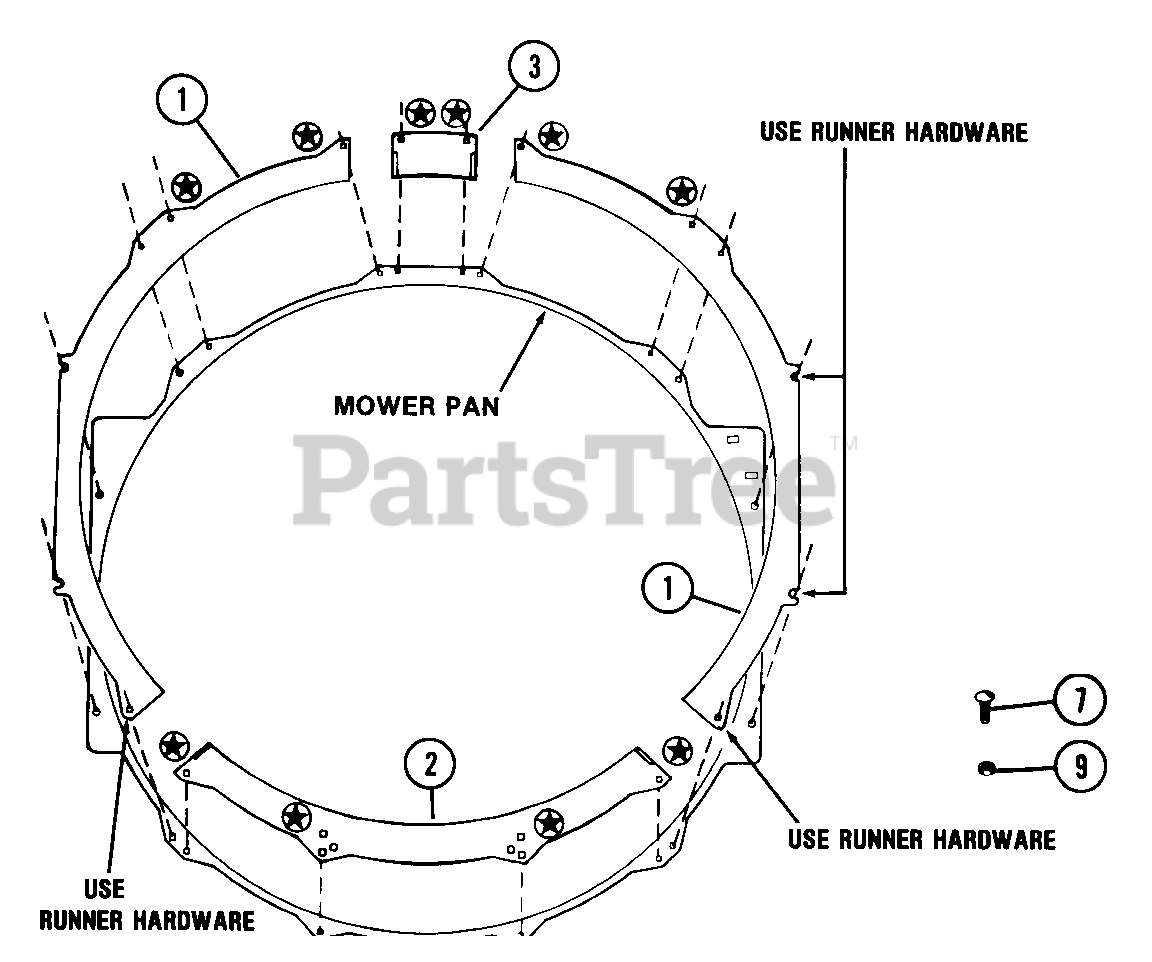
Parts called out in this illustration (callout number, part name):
1	32 IN SIDE FLANGE
2	BACK FLANGE
3	FRONT CLAMP
7	BLT-RDHDSQNK .25-20X.62 PL
9	NUT-LK-CTR .250-20 PL
